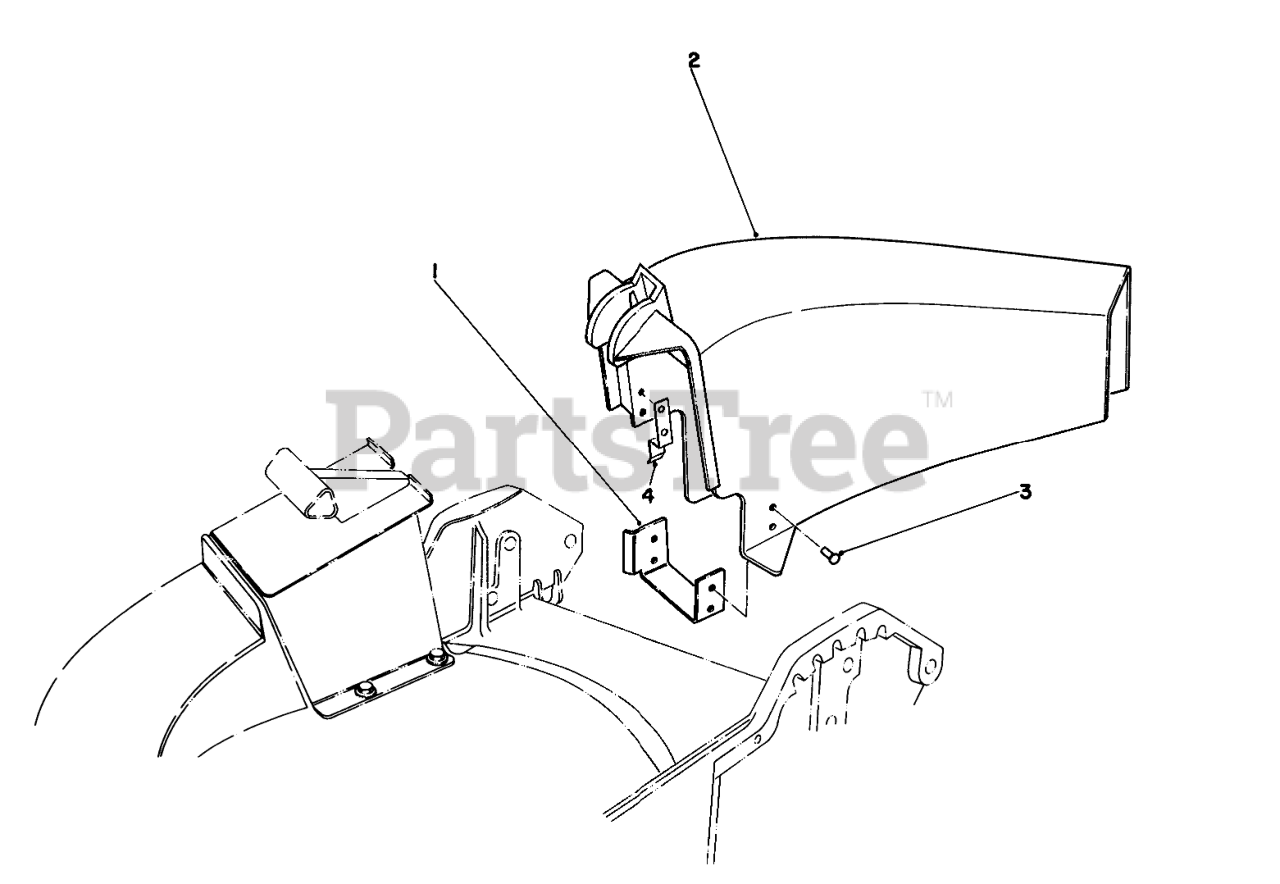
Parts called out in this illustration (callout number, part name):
1	CHUTE BRACKET
2	Chute Discharae
3	RIVET
4	CHUTE TAB
